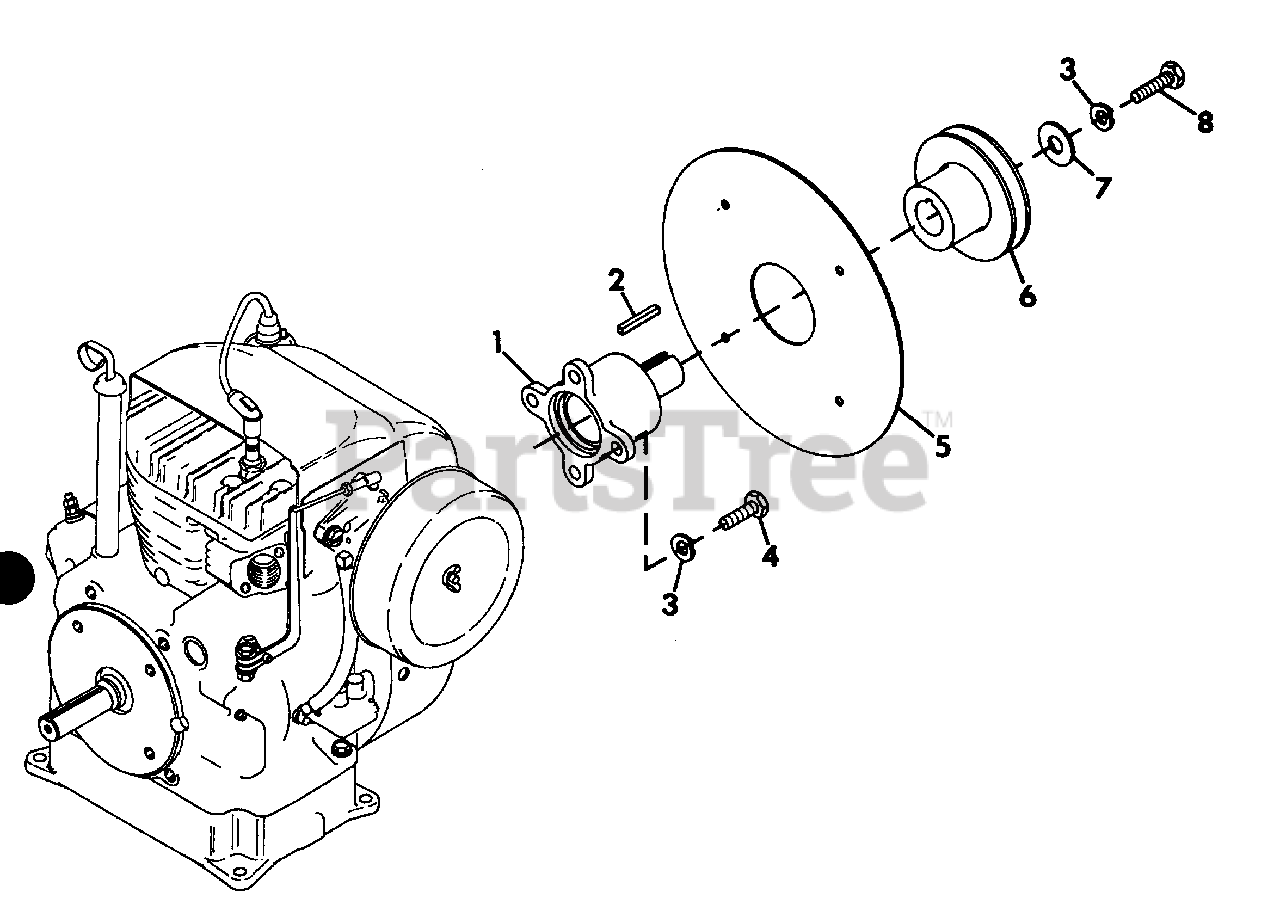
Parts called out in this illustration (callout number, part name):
1	ADAPTOR, DRIVE KOHLER
2	KEY, SQUARE .250X1.250
3	WASHER, LOCK 3/8
4	BOLT, HEX 3/8-16X1.00
5	SCREEN, GRASS KOHLER
6	SHEAVE, ENGINE
7	WASHER, FLAT 1.25X.50 HARD
8	BOLT, HEX 3/8-16X1.25
